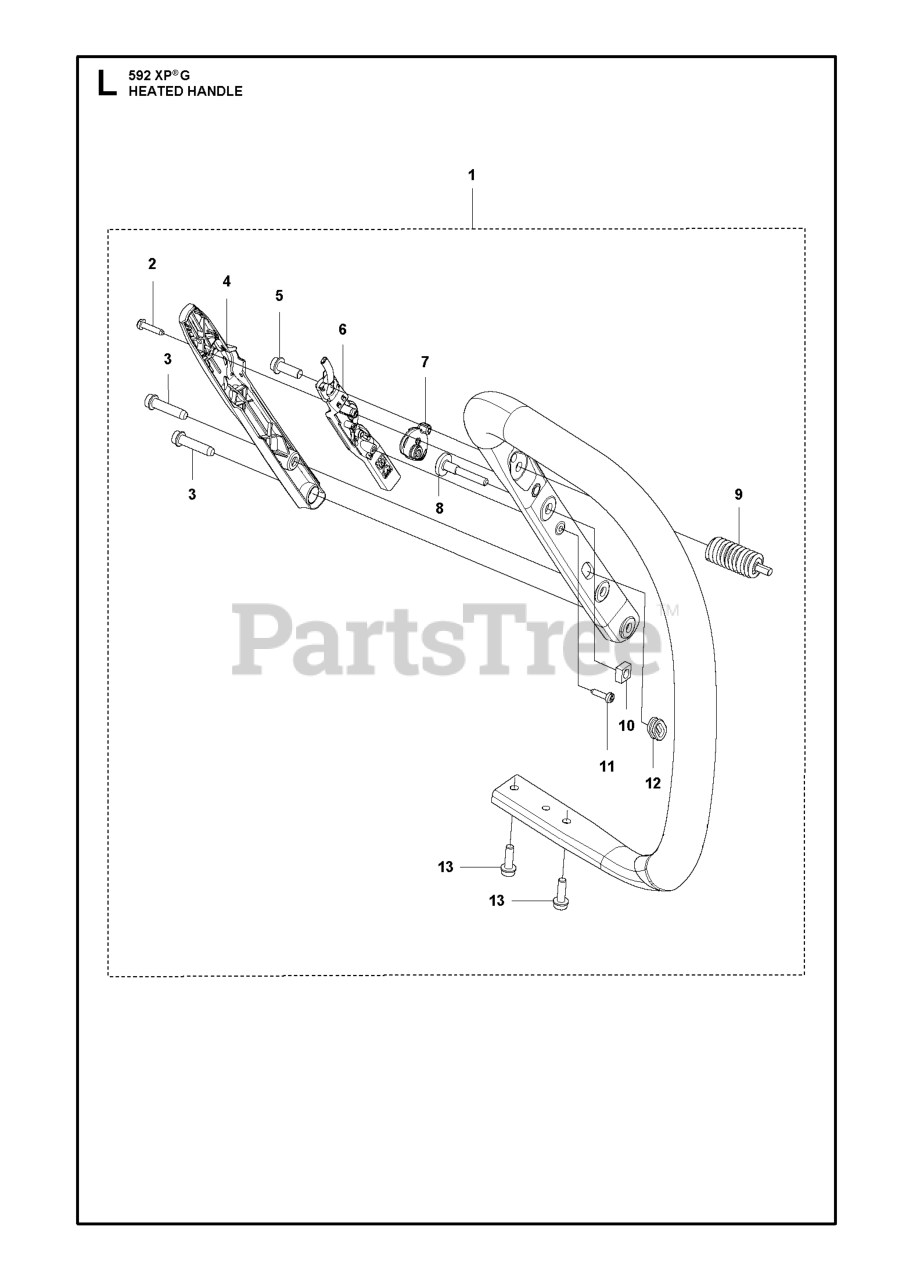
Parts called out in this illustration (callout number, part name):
1	HANDLE SYSTEM XPG
2	SCREW CITXPANT HEXABULAR SOCKE
4	COVER FRONT HANDLE HEAT
5	SCREW ITXSCFM
6	CONTACT PLATE FRONT HANDLE HE
8	SCREW ITXPANM MOVEMENT LIMITER
9	ANTIVIBRATION ELEMENT CYLINDE
11	SCREW CITXPANT
